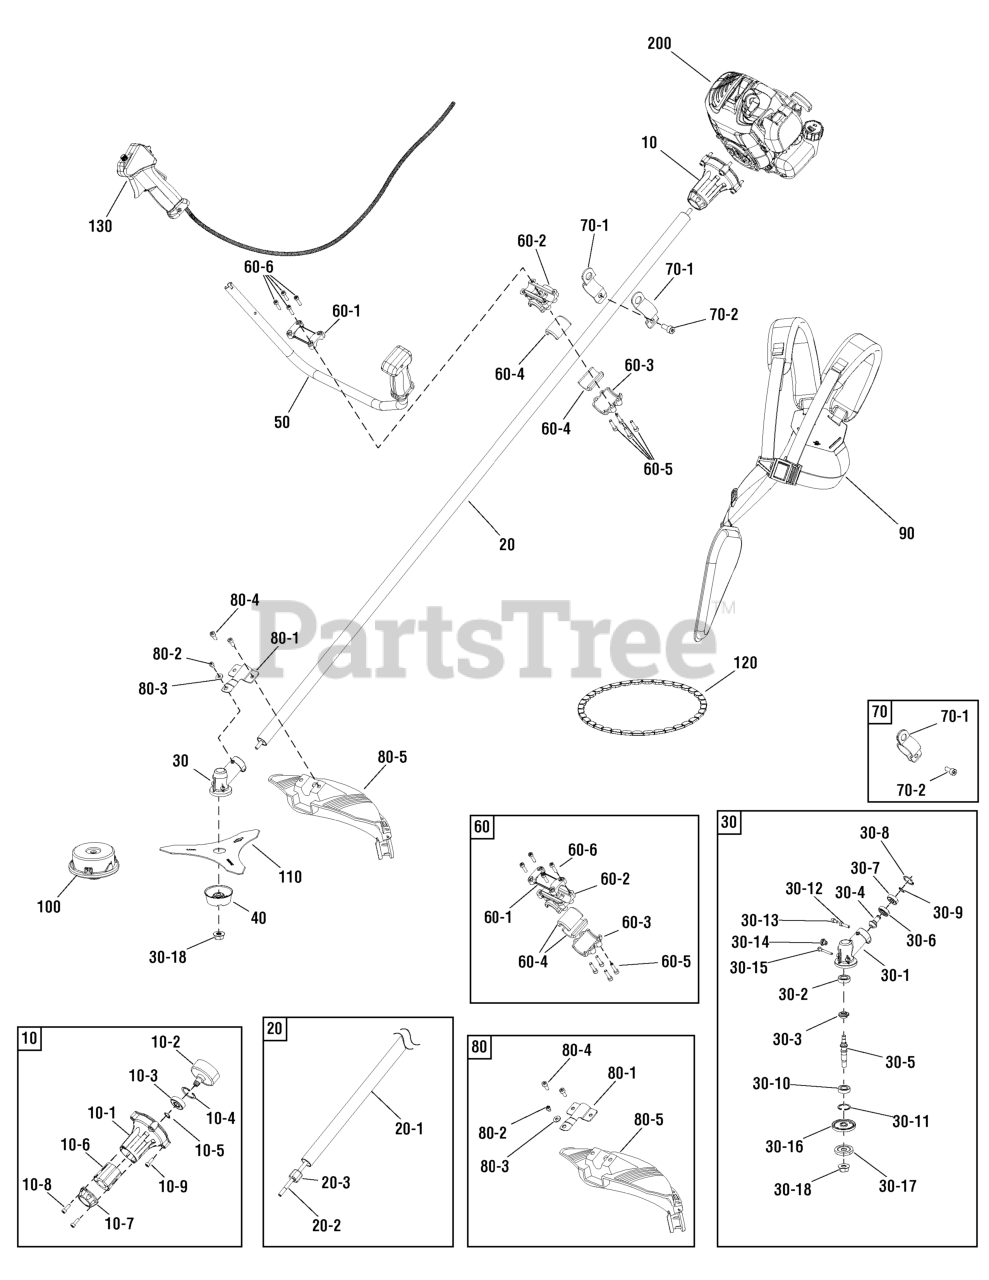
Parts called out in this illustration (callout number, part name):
10	CLUTCH HOUSING ASSEMBLY
10-1	HOUSING, Clutch
10-2	CLUTCH DRUM
10-3	BEARING
10-6	COUPLER
10-7	COVER
20	SHAFT ASSEMBLY
20-1	SHAFT
20-2	DRIVE SHAFT
20-3	BUSH
30	GEARBOX ASSEMBLY
30-1	HOUSING, Gear Case
30-2	BEARING
30-3	GEAR
30-4	PINION
30-5	SHAFT
30-6	BEARING
30-7	BEARING
30-10	BEARING
30-14	PLUG
30-15	BOLT
30-16	BLADE HOLDER
30-17	BLADE HOLDER
30-18	NUT
50	HANDLE ASSEMBLY
60	HANDLE BRACKET ASSEMBLY
60-1	BRACKET, Handle, Upper
60-2	BRACKET, Handle, Lower
60-3	BRACKET, Shaft
60-4	BUSH
70	HANGER ASSEMBLY
70-1	HANGER
80	GUARD ASSEMBLY
80-1	BRACKET
80-2	BOLT
80-3	WASHER
80-5	GUARD
90	SHOULDER STRAP
100	BUMP HEAD
110	BLADE, 3T
120	COVER, Blade
130	LEVER ASSEMBLY, Throttle
200	ENGINE
